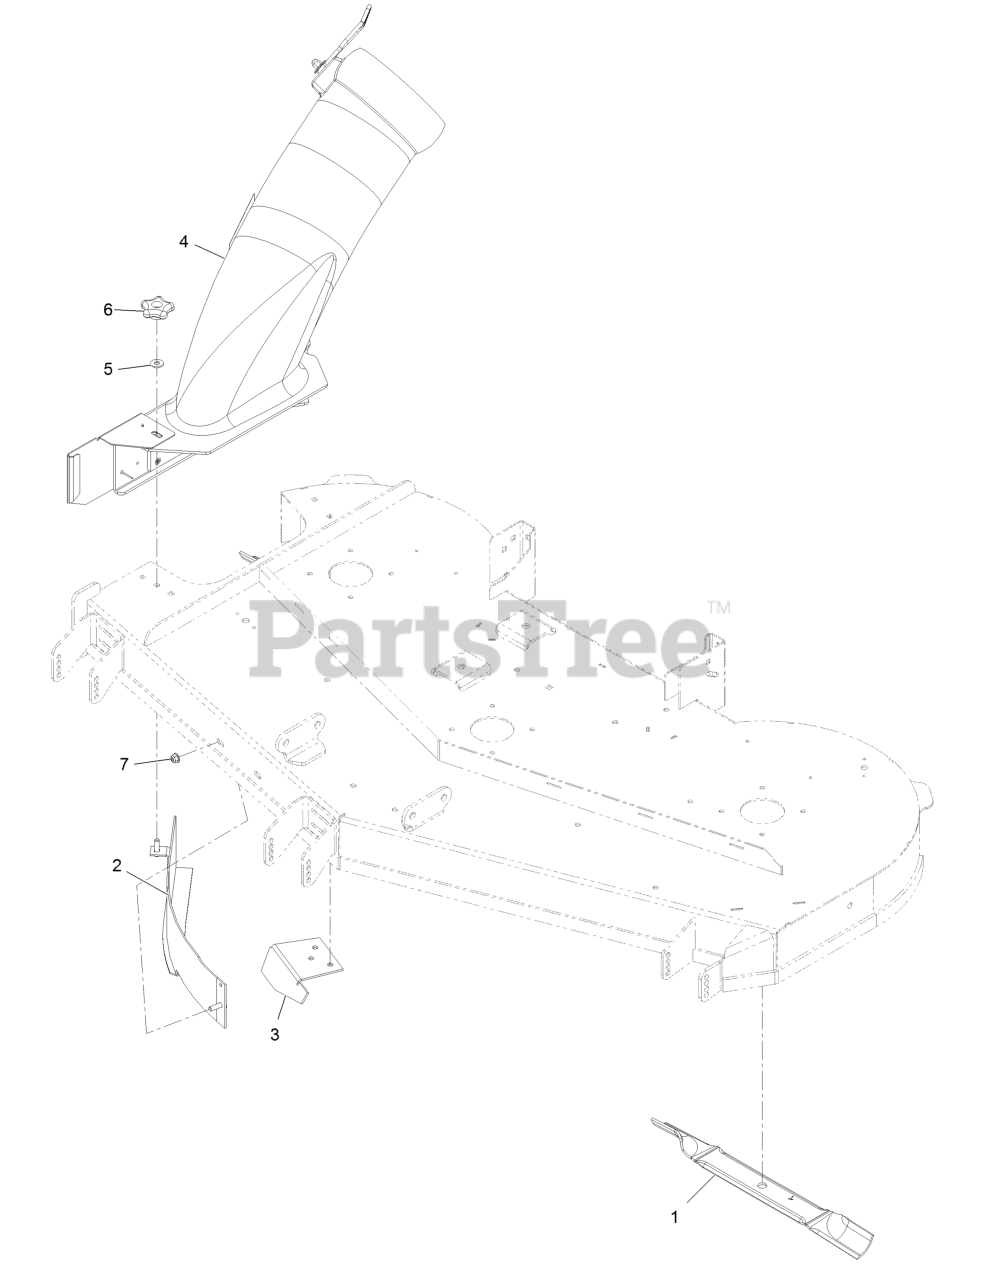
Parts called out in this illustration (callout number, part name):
1	BLADE-20.50 INCH
2	BAFFLE ASM
3	Baffle-Cutoff
4	BAGGER BOOT ASM
5	WASHER-FLAT
6	KNOB-HANDLE
7	NUT-HF, NI
